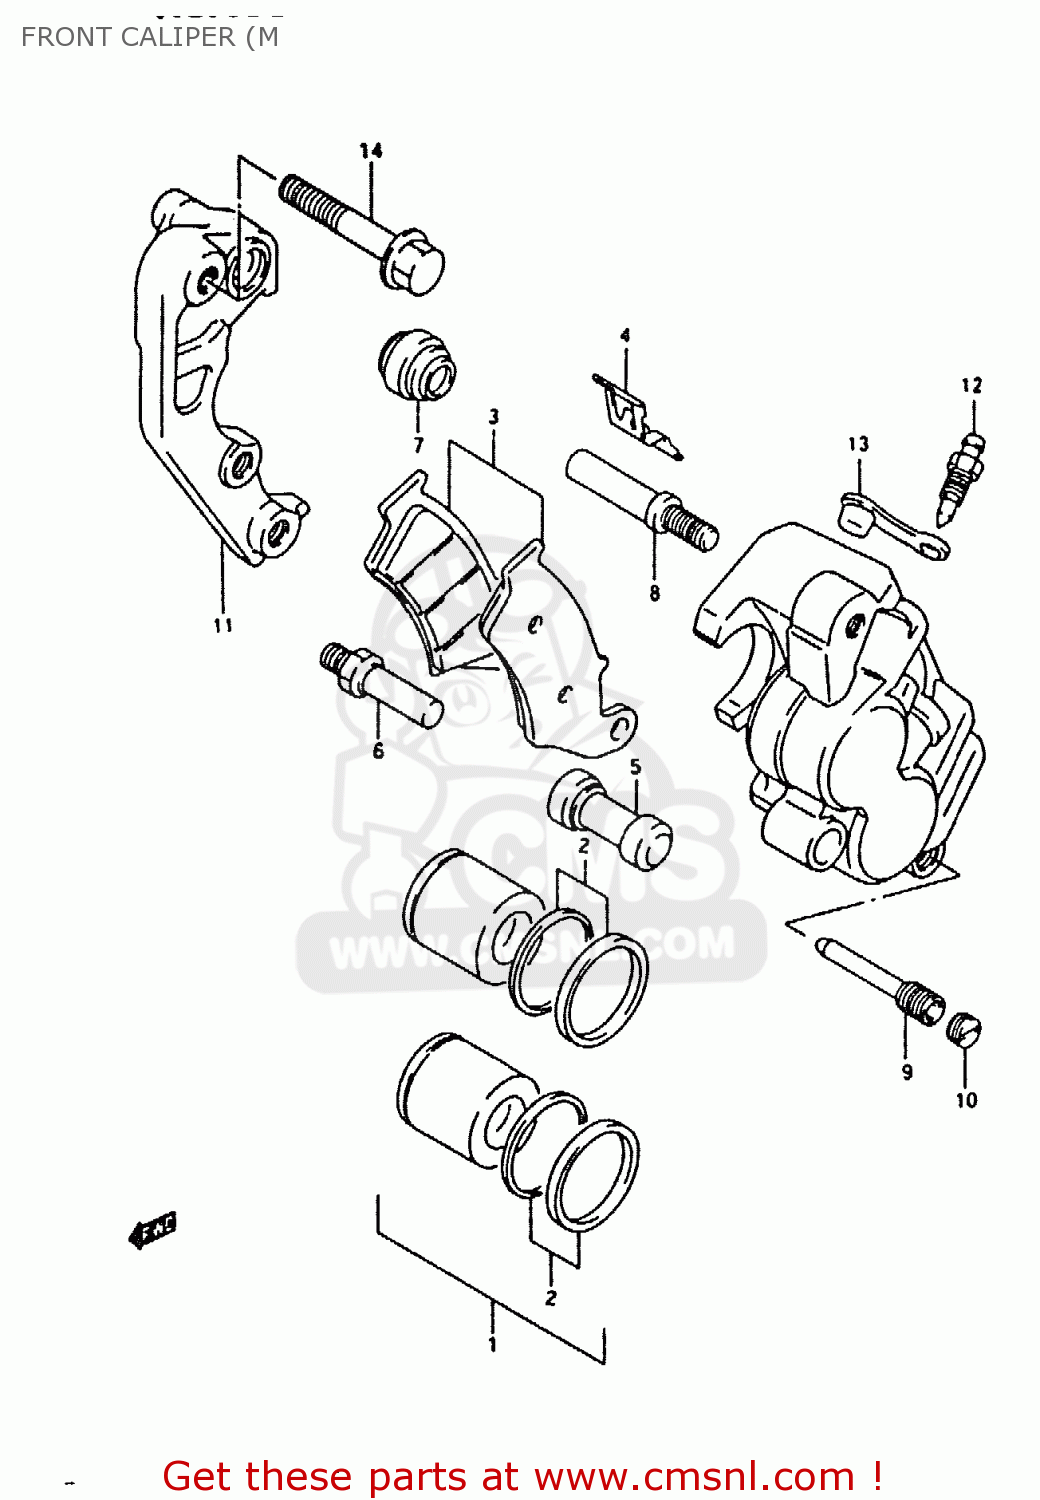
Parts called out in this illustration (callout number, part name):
1	PISTON SET
2	SEAL SET,PISTON
3	PAD SET (NAS)
4	SPRING,PAD
5	BOOT
6	PIN,BOLT
7	PIN
8	PIN,HANGER
10	PLUG,PIN
11	BRACKET
12	BLEEDER
13	BRACKET
14	BLEEDER
15	CAP,BLEEDER
16	BOLT (8*35)
